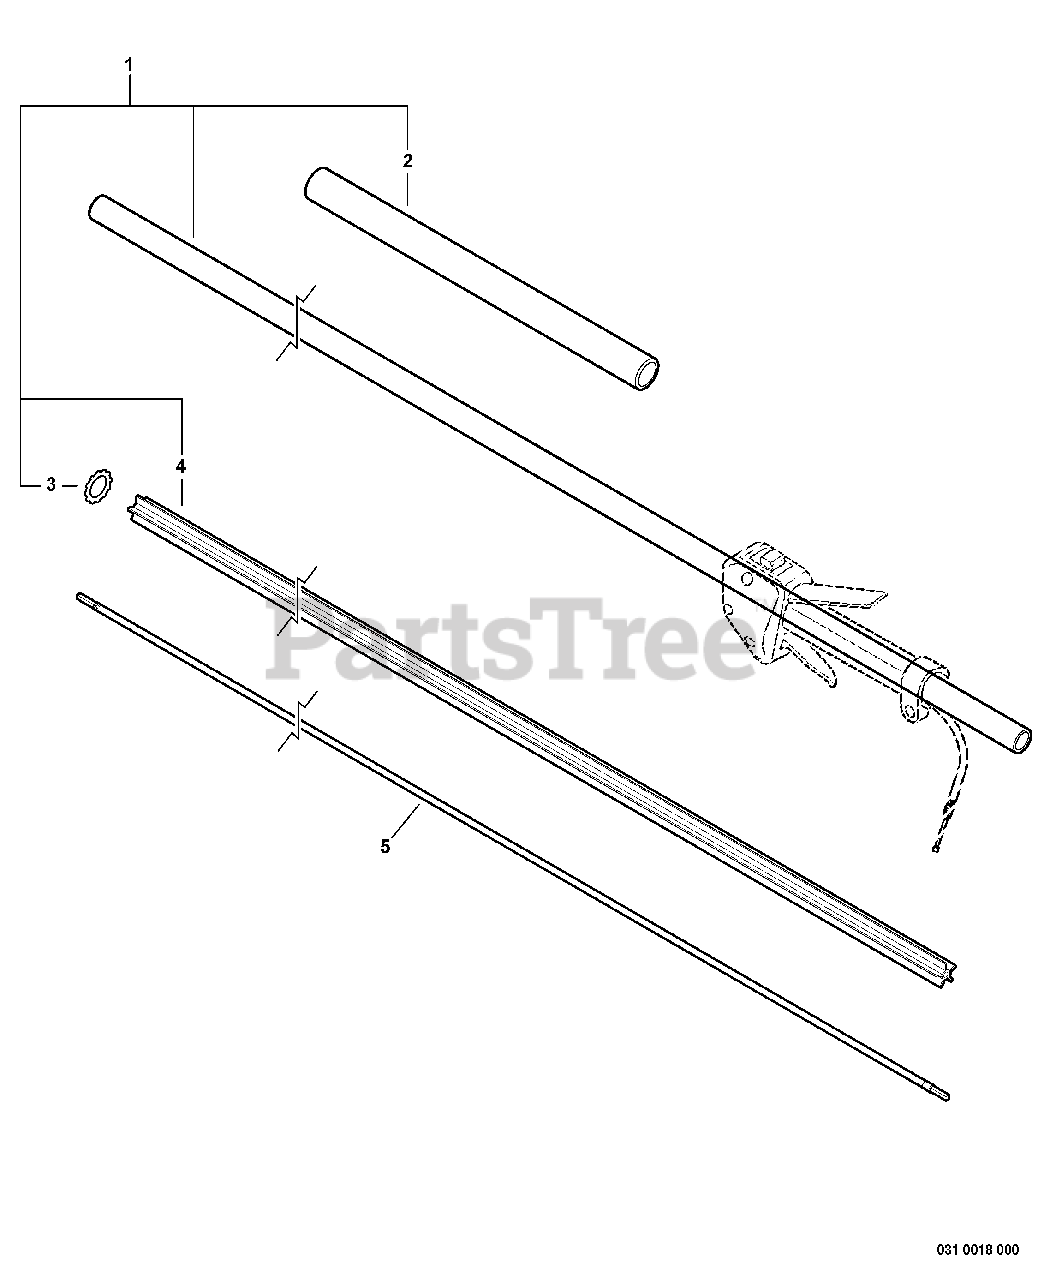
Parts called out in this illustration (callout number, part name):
1	MAIN PIPE ASSY
2	GRIP, FRONT - LEFT
3	LOCKWASHER - EXTERNAL
4	LINER - FLEXIBLE
5	DRIVESHAFT - FLEXIBLE
